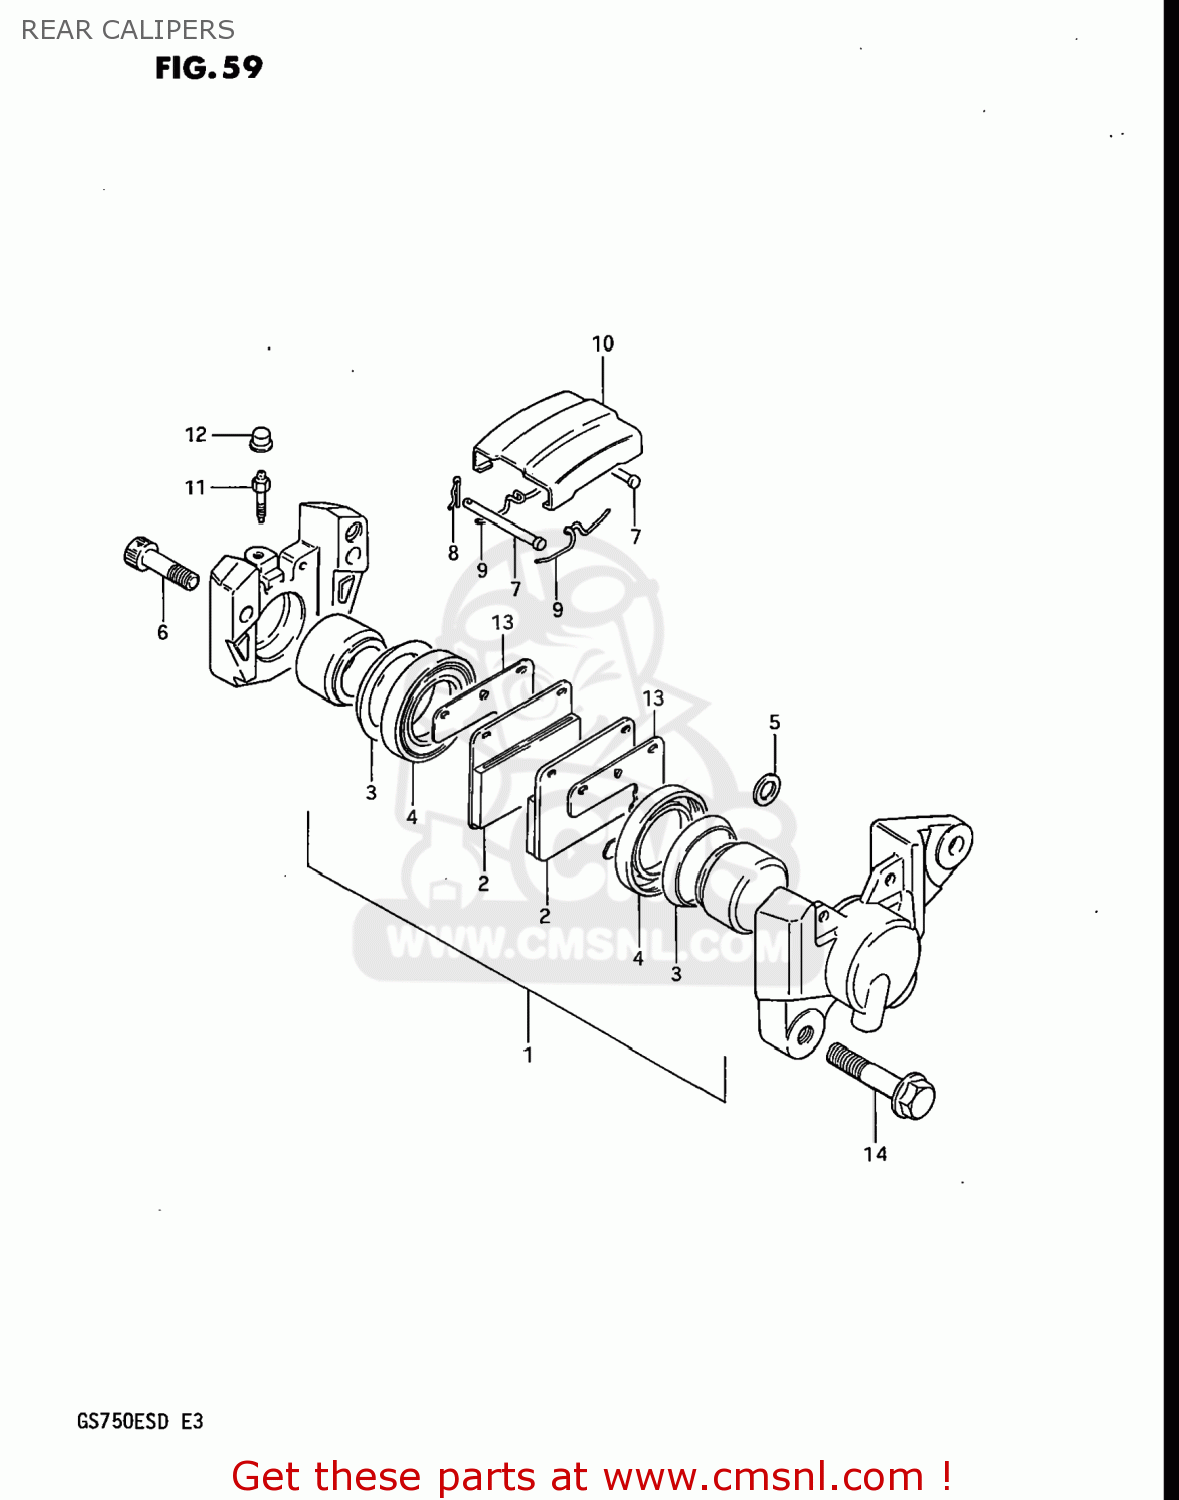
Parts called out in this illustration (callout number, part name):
1	PISTON SET
2	PAD,BRAKE (MCA)
3	SEAL,PISTON
4	BOOT,PISTON
5	SEAL,JOINT
6	BOLT,CALIPER HOUSING
7	PIN,PAD
8	CLIP,PAD PIN
9	SPRING
10	COVER,DUST
11	BLEEDER
12	CAP,BREATHER
13	SHIM,RR CALIPER
14	BOLT
